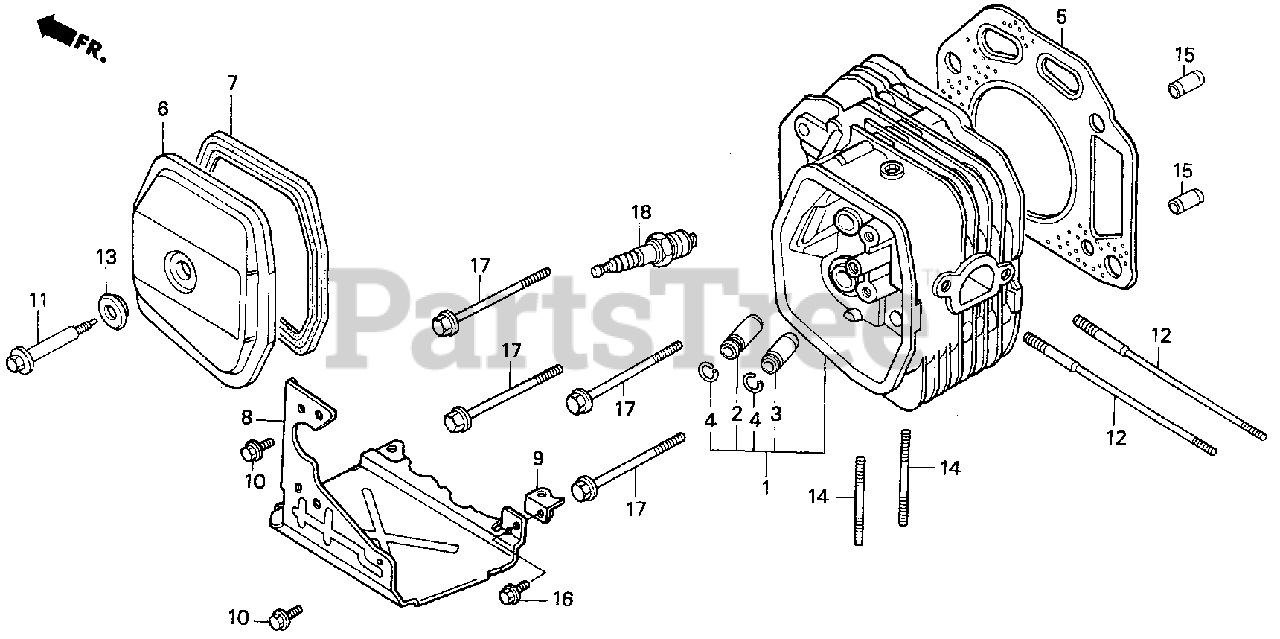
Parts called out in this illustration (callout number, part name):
1	CYLINDER HEAD
2	GUIDE, VALVE (OS)
3	GUIDE, EX. VALVE (OS)
4	CLIP, VALVE GUIDE
5	GASKET, CYLINDER HEAD
6	COVER, HEAD
7	GASKET, CYLINDER HEAD COVER
8	COVER (LOWER)
9	STAY, COVER (LOWER)
10	BOLT, FLANGE (6X12) (CT200)
11	BOLT, HEAD COVER
12	BOLT, STUD (8X131.5)
13	WASHER, HEAD COVER
14	BOLT, STUD (8X32)
15	PIN A, DOWEL (12X20)
16	BOLT, FLANGE (6X12)
17	BOLT, FLANGE (10X80)
18	SPARK PLUG (BPR5ES) (NGK)
18	SPARK PLUG (W16EPR-U) (DENSO)
